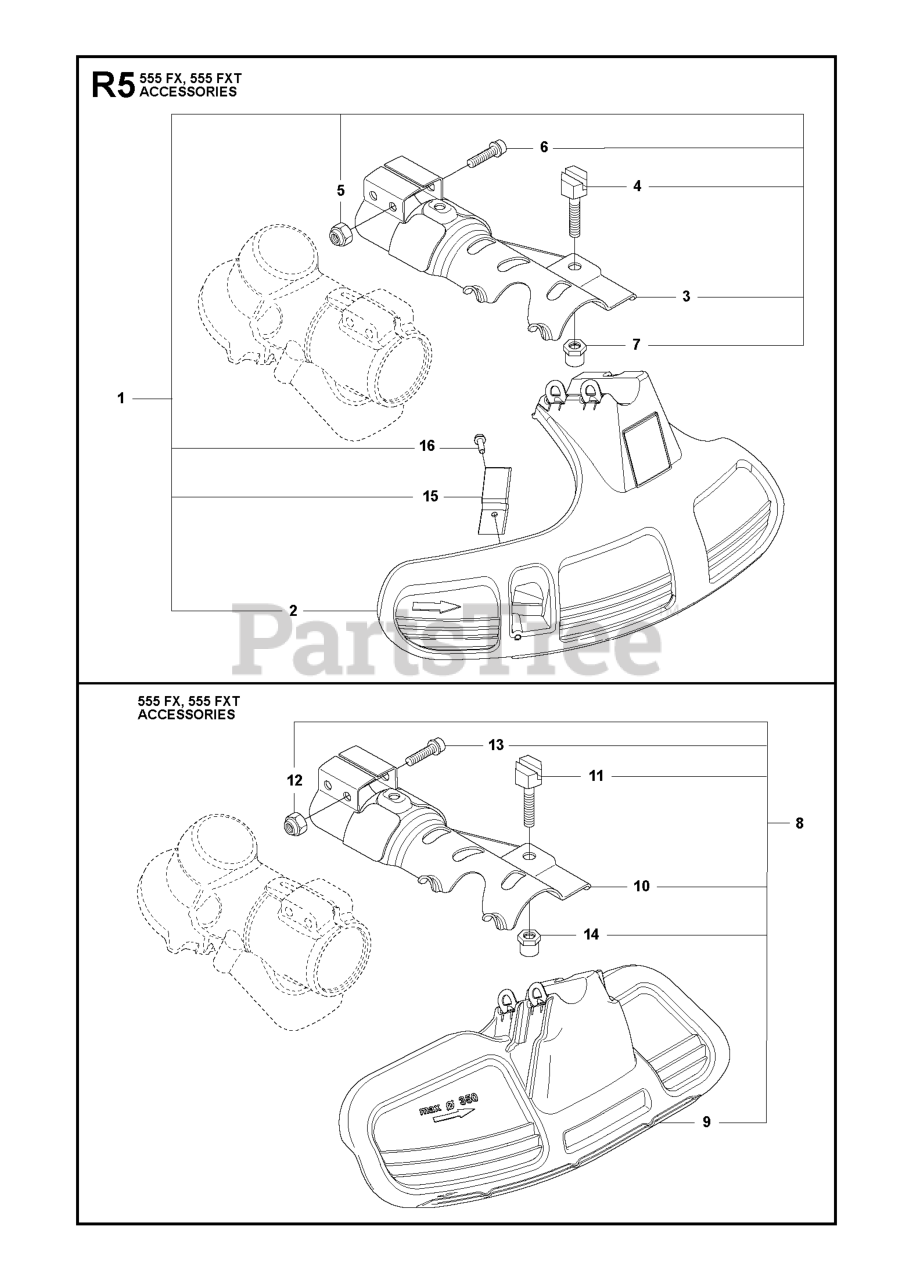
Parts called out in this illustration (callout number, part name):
1	GUARD ASSY
2	PROTECTION
3	ATTACHMENT PLATE
5	LOCKNUT M6
7	SPACING SLEEVE
8	GRASS BLADE GUARD ADAPTER INCL
9	BLADE GUARD GRASS
10	ATTACHMENT PLATE
12	LOCKNUT M6
14	SPACING SLEEVE
16	SCREW IHSCFT
